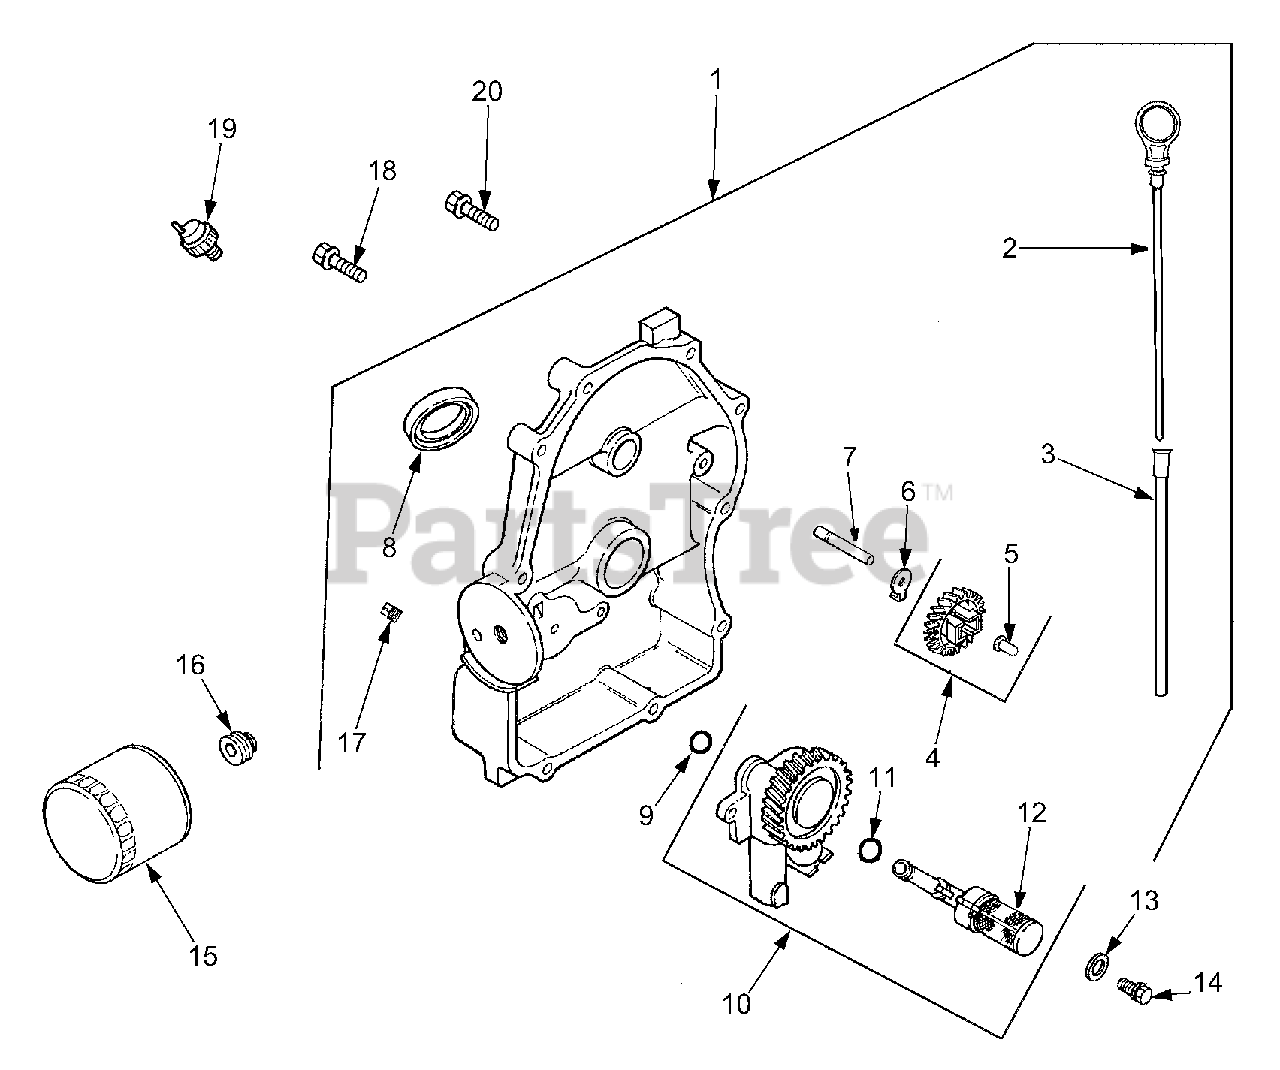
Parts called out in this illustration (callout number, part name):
1	Plate, Closure Assembly
3	Tube, Dipstick
4	Kit, Governor Gear
5	Pin, Governor Regulating
6	Tab, Locking
7	Shaft, Governor Gear
8	Seal, Oil (PTO End)
10	Oil Pump Assembly
11	O-Ring, Oil Pick-Up
12	Pick-Up, Oil
13	Washer, Plain
14	Screw, Hex Flange M6 x 1 x 25
15	Filter, Oil
16	Nipple, Oil Filter
17	Plug, Pipe 1/8"
18	Screw, Hex Flange M8 x 1.25 x 45
19	Switch, Pressure
20	Screw, Hex Flange M8 x 1.25 x 45
